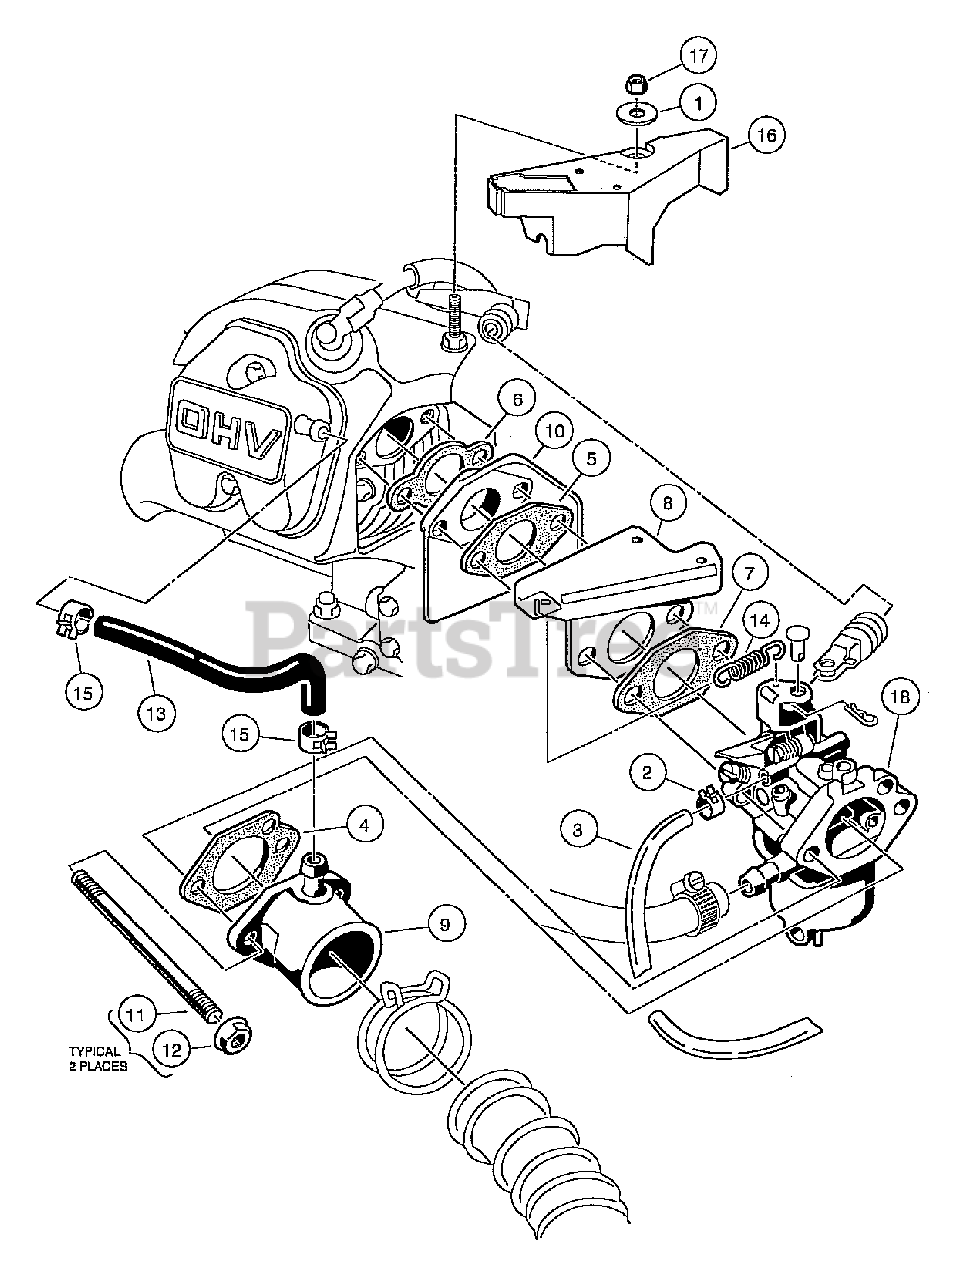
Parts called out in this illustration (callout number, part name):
1	Washer, 5/16 Flat
2	Clamp, 0.301 ID Hose
3	Fuel Line
4	Gasket, Garb To Intake Manifold
5	Gasket, Insulator
6	Gasket, Engine To Insulator
7	Gasket, Sprg Brkt To Garb OHV
8	Bracket, Throttle Spring Return
9	Pipe, Intake Manifold
10	Insulator, Carburetor
11	Stud, M6-1.00 Two-Ended
13	Tube, Crankcase Vent
14	Spring, Throttle Return
16	Shield, Governor
17	Locknut, M6-1.00 Nylon Insert
18	Carburetor Assembly, FE290D
19	Jet, Altitude, # 82
20	Gasket, Carburetor Bowl OHV
21	Float Assembly
22	Screw Assembly
24	Chamber Assembly, Float
25	Screw Assembly
26	Jet, #40 Pilot
27	Nozzle, Main
28	Assembly, Pilot Air Screw
